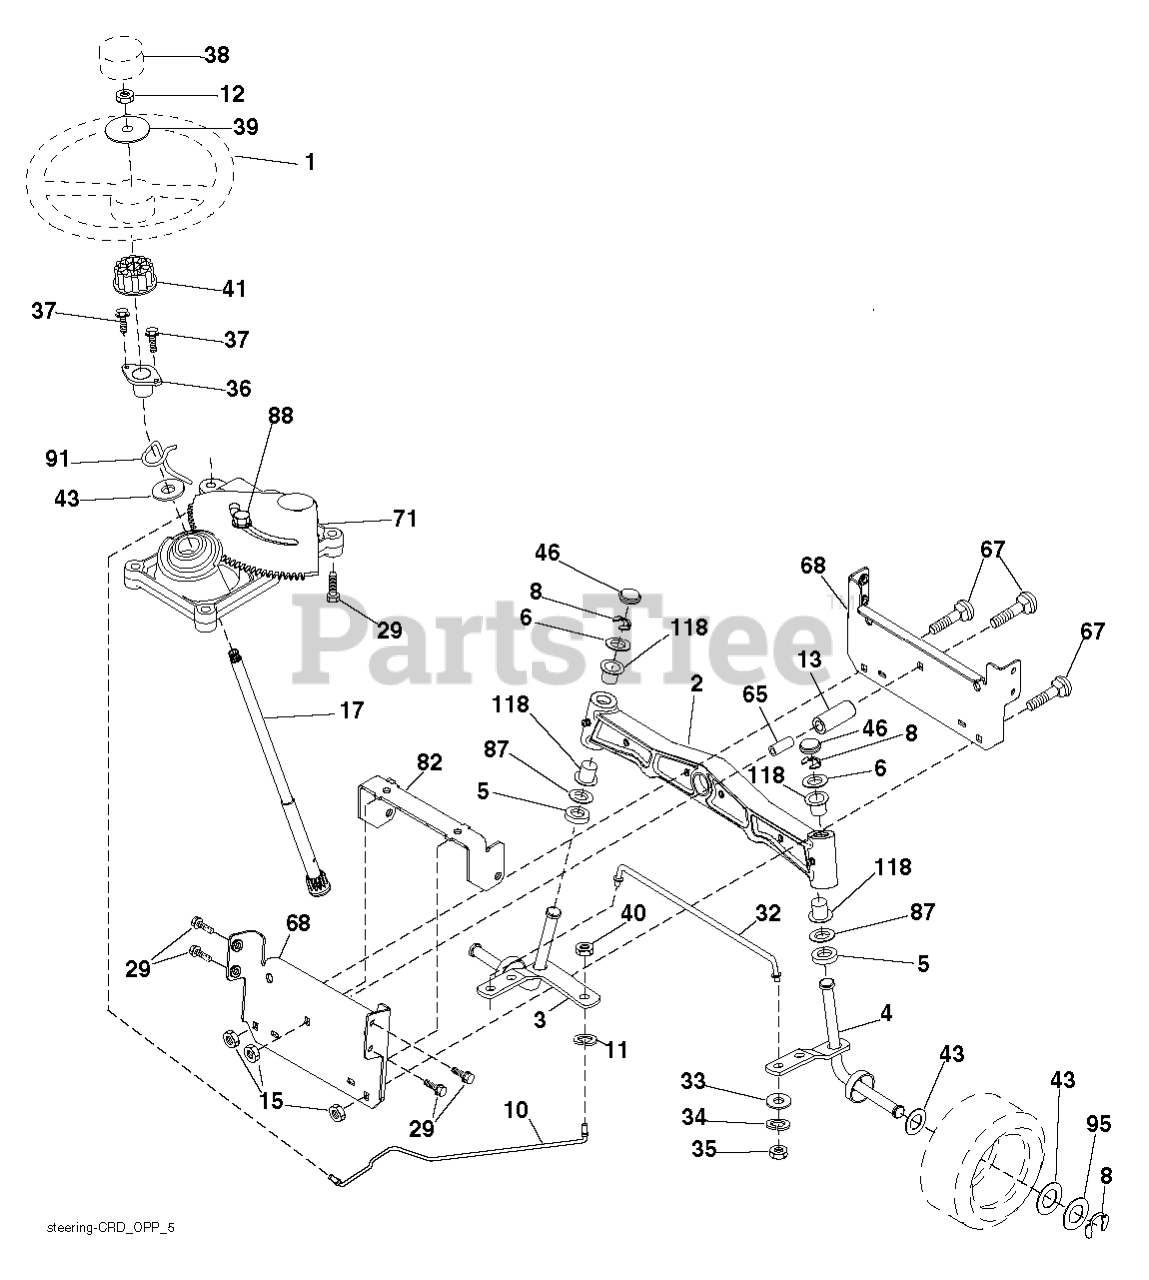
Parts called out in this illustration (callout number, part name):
1	WHEEL.STEER.HUSQ.SR.498.OVMLD
2	AXLE.ASM.LT.CAST.LGHTWGHT
3	SPINDLE.ASM.LH.15"TIRES
4	SPINDLE.ASM.RH.15"TIRES
5	THRUST WASHER
10	DRAGLINK.15".TIRES.2001
11	WASHER, LOCK 3/8
12	NUT.HEX.1/2-20
13	TUBE, PIVOT AXLE
15	NUT LOCK FLG 3/8-16 UNC
17	SHAFT ASM STRG
29	SCREW, 3/8-16X3/4
33	WASHER M
34	WASHER.LOCK.HVY.HLCL.SPR.5/16
35	NUT, CROWNLOCK
36	BUSHING, STRG. BLK
37	SCREW.TT.#10-32X.5.3/8.FLANGE
38	INSERT.CAP.WHL.STRG.HUSQ.PREM
39	WASHER 9/16"ID, 2 3/8"OD
40	NUT CROWNLOCK 3/8-24
41	ADAPTER, WHEEL STNG..
46	CAP.SPINDLE.BLACK
65	SPACER.BRACE.AXLE
67	BOLT CARRIAGE
68	BRACE.AXLE.15"TIRES
71	STEERING ASM
82	BRACKET.SUSP.CHASSIS.FRONT.15
87	WASHER, FLAT .781 X 1 1/2"
88	BOLT, SHOULDER 7/16-20
91	CLIP.STEERING
95	WASHER.HARDENED
118	BUSHING, AXLE CAST
